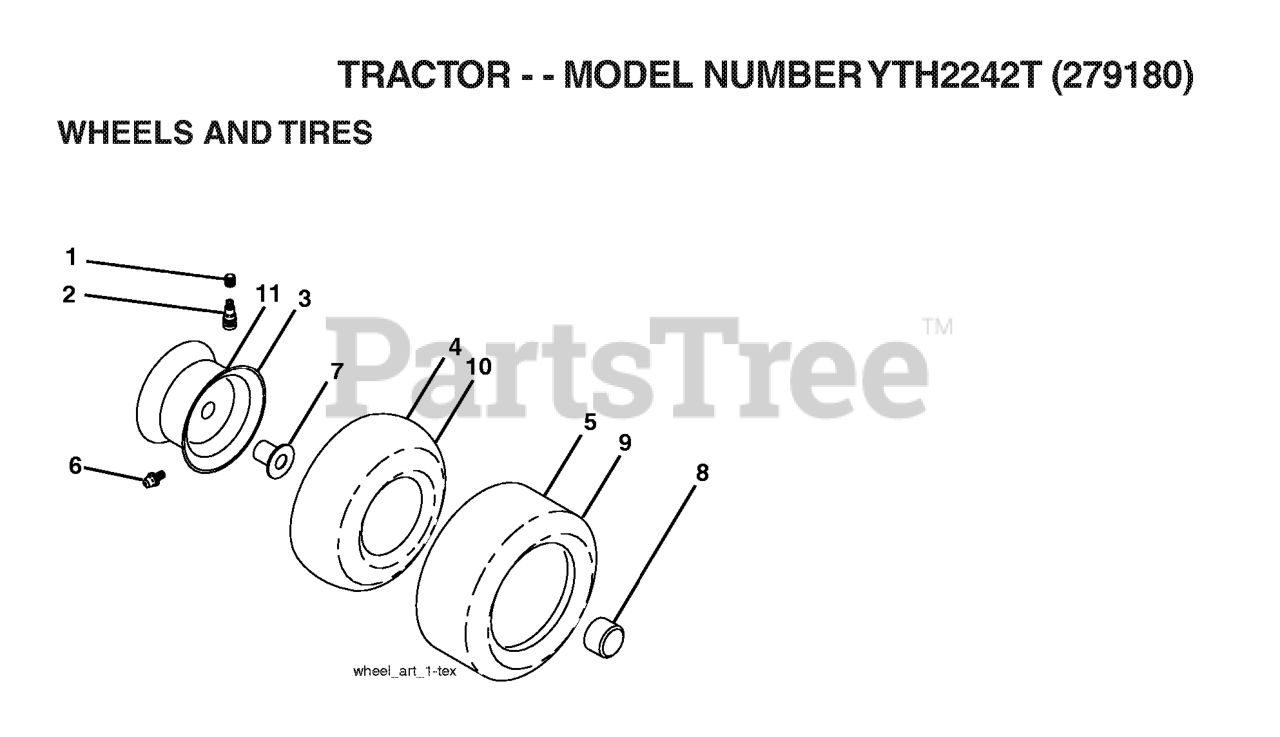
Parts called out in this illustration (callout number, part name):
2	VALVE STEM LT
3	RIM ASM 6" FRONT SILVER
4	TUBE.5.3/4.5/6
5	TIRE HEAVY DUTY
6	FITTING LT
7	BEARING T
8	CAP, AXLE BLK
9	TIRE.20X8-8.TURF.SAVER
10	TUBE
11	RIM ASM 8" REAR SILVER
